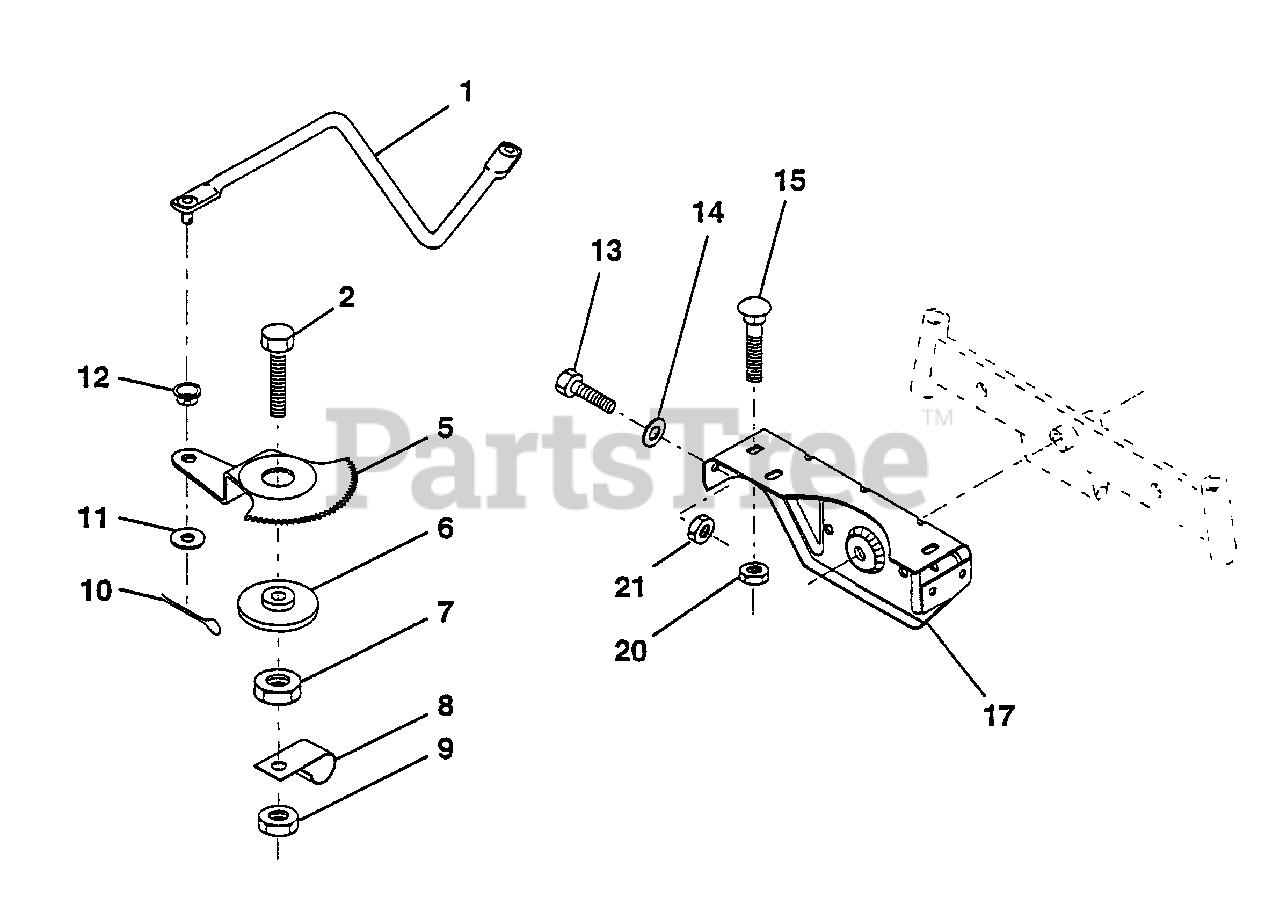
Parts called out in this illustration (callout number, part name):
1	Link, Drag
2	Bolt, Hex, Fin. 1/2-13 x 1-3/4
5	Gear, Sector
7	Nut, Heavy Hex, Top Lock 1/2-13 UNC
8	Clip, Insulated
9	Nut, Crownlock 3/8-16
10	Pin, Cotter 1/8 x 3/4
11	Washer 13/32 x 13/16 x 16 Gauge
13	Bolt, Hex Head 5/16-18 UNC x 1
14	Washer 11/32 x 7/8 x 16 Gauge
15	Bolt, Carriage 3/8-16 UNC x 3/4
17	Support, Front Axle
20	Nut, Hex, Lock Hex w/wsh 3/8-16
21	Nut, Hex, Lock Hx w/Ins 5/16-18
